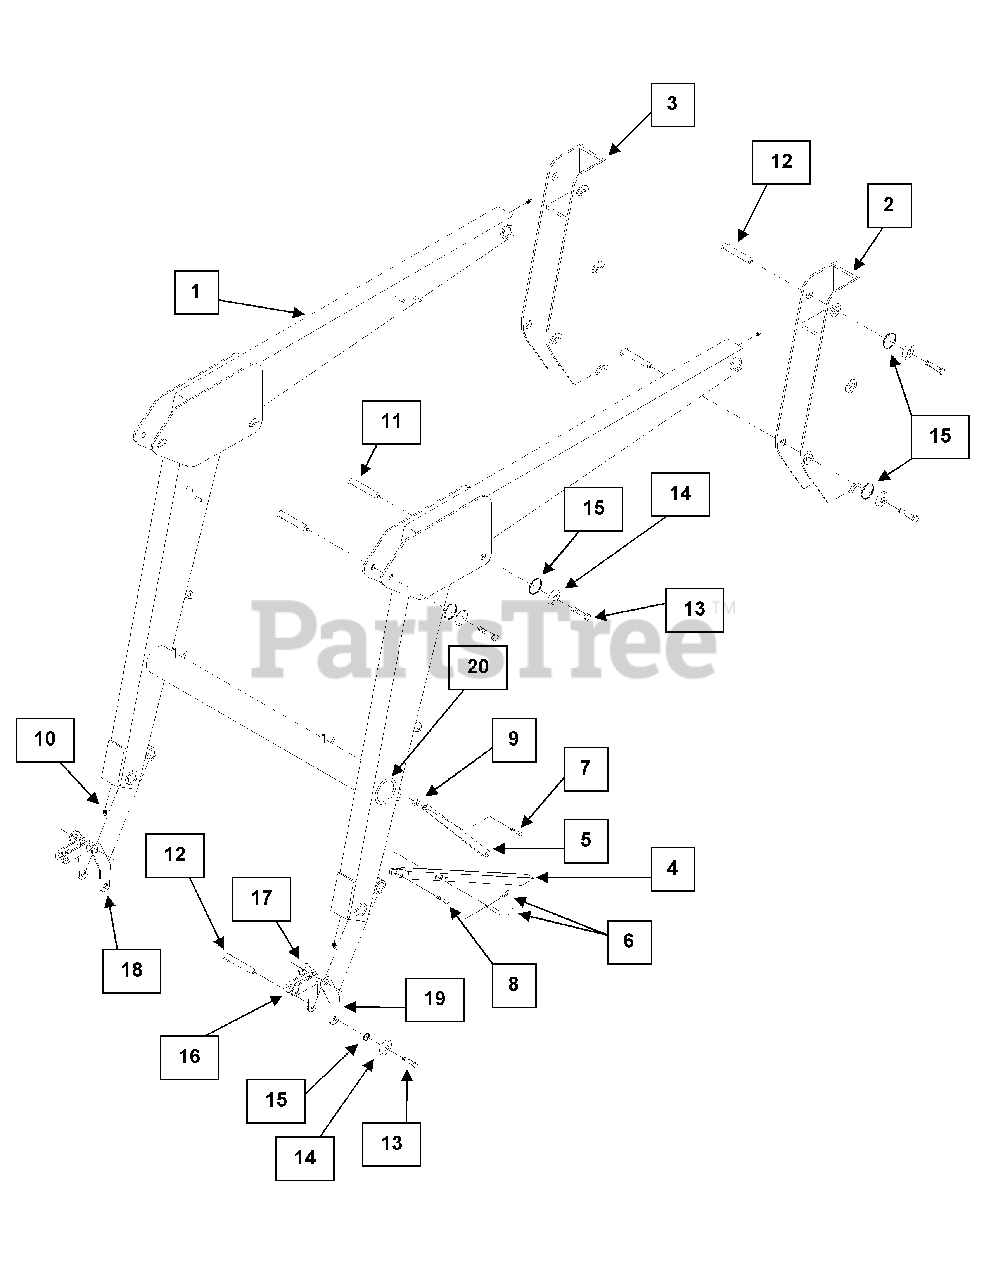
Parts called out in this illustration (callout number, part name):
1	Boom Assembly
2	Bearing Box, LH
3	Bearing Box, RH
5	Parking Leg Brace
6	Bent Pin W/Hitch Pin Clip
7	Hex Head Cap Screw, 3/8" x 1 1/2"
8	Hex Head Cap Screw, 3/8" x 1 1/4"
9	Hex Head Lock Nut, 3/8"
10	Grease Fitting
11	Pivot Pin, 1" x 70mm
12	Pivot Pin, 1" x 87mm
13	Hex Head Cap Screw, 5/16" x 3/4"
16	Bucket Linkage Assembly
17	Boom Linkage Assembly, LH
18	Boom Linkage Assembly, RH
19	Boom Linkage
20	Crosstube Cover
